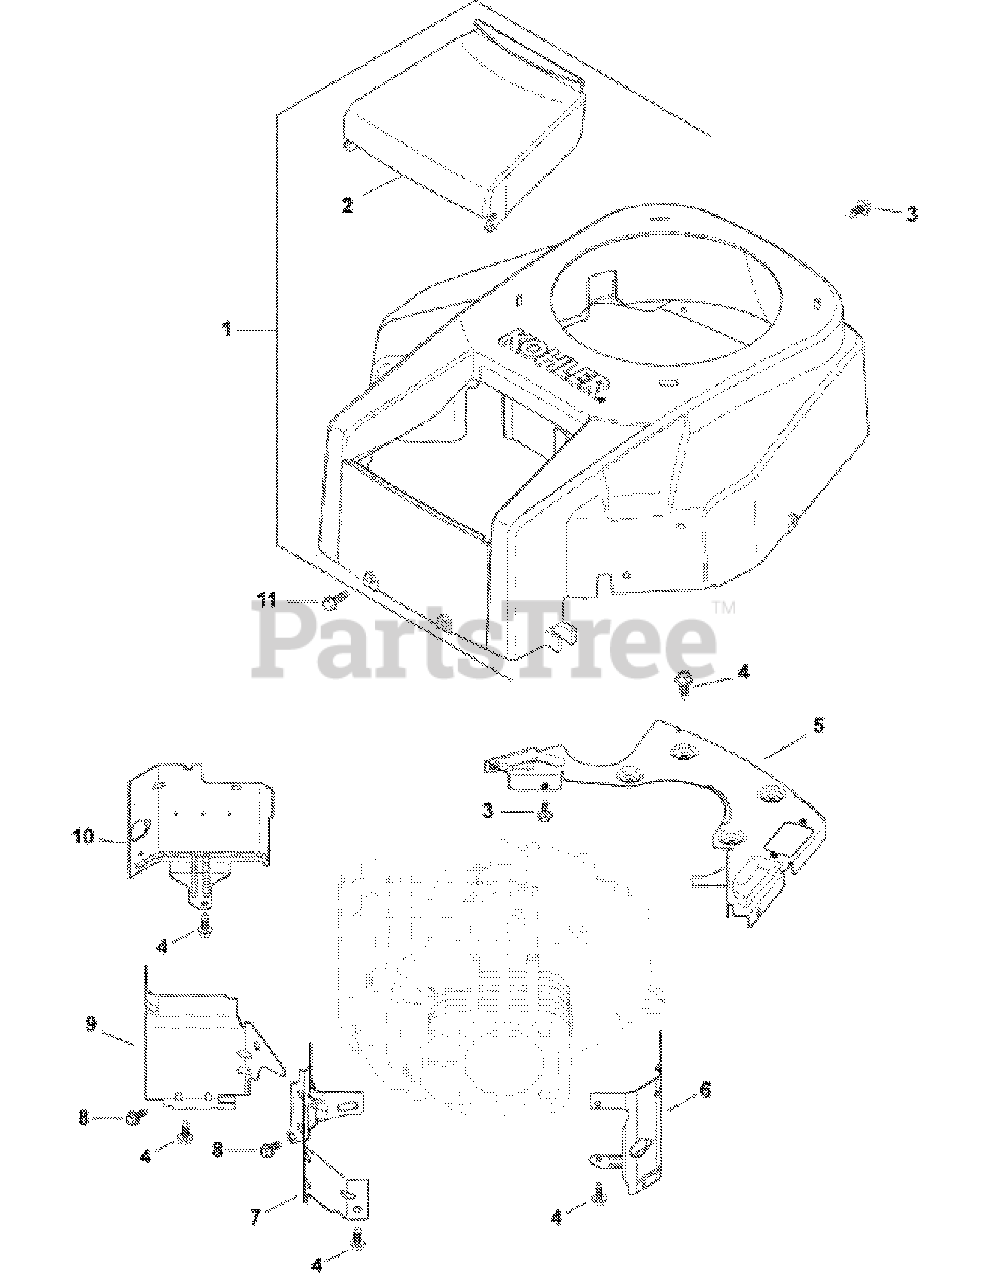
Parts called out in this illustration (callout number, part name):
1	KIT, HOUSING BLOWER
2	COVER, AIR CLEANER
3	SCREW, FLG THD FRM M5X.8X16
4	SCREW, FLG THD FRM M6X1.0X16
5	KIT, BACKING PLATE
6	BAFFLE, CYL BARREL - #2 SIDE
7	BAFFLE, VALLEY #2 SIDE
8	SCREW, FLG THD FRM M5X.8X10
9	BAFFLE, VALLEY #1 SIDE
10	BAFFLE, CYL BARREL - #1 SIDE
11	SCREW, TAP M6X1.7X18
